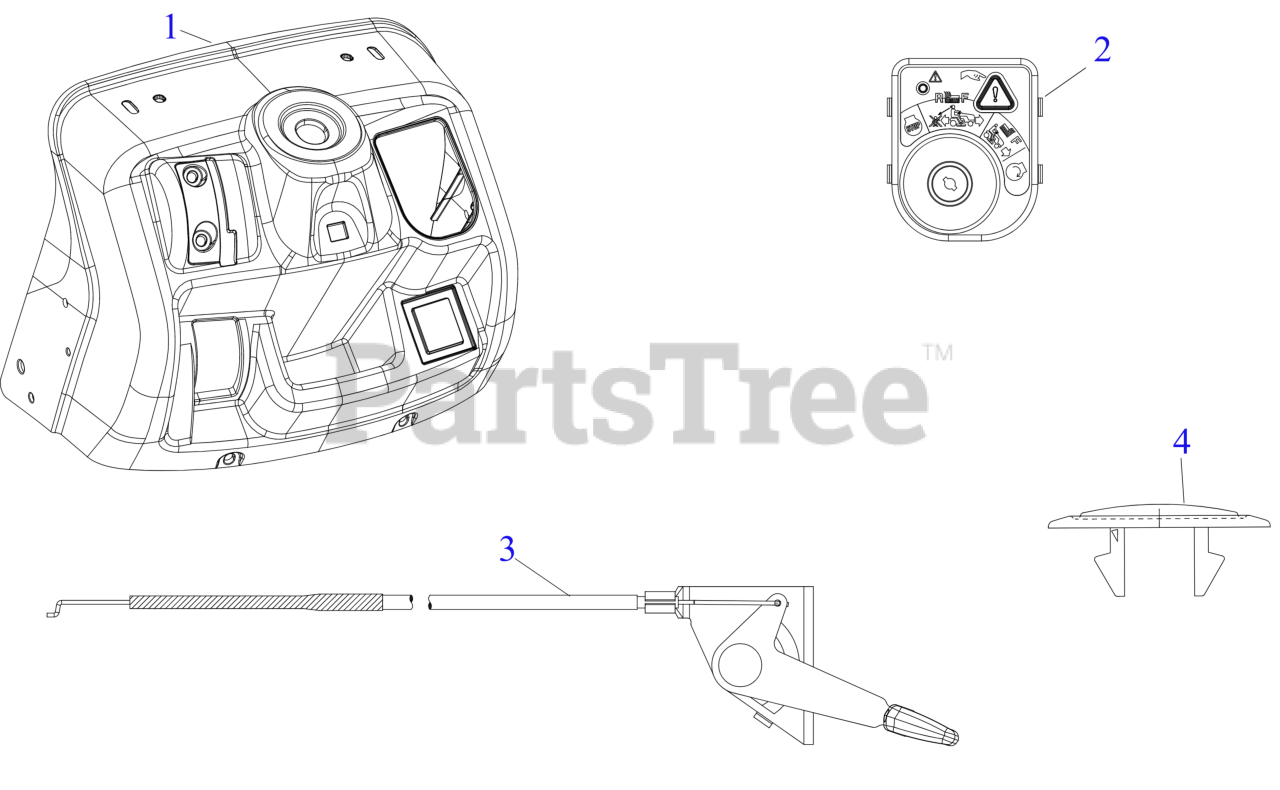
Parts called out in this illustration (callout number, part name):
1	UPPER DASH
2	IGNITION MODULE SWITCH RMC (MAN PTO BLK)
3	THROTTLE CABLE 31" x 1.1
4	CHOKE PLUG
